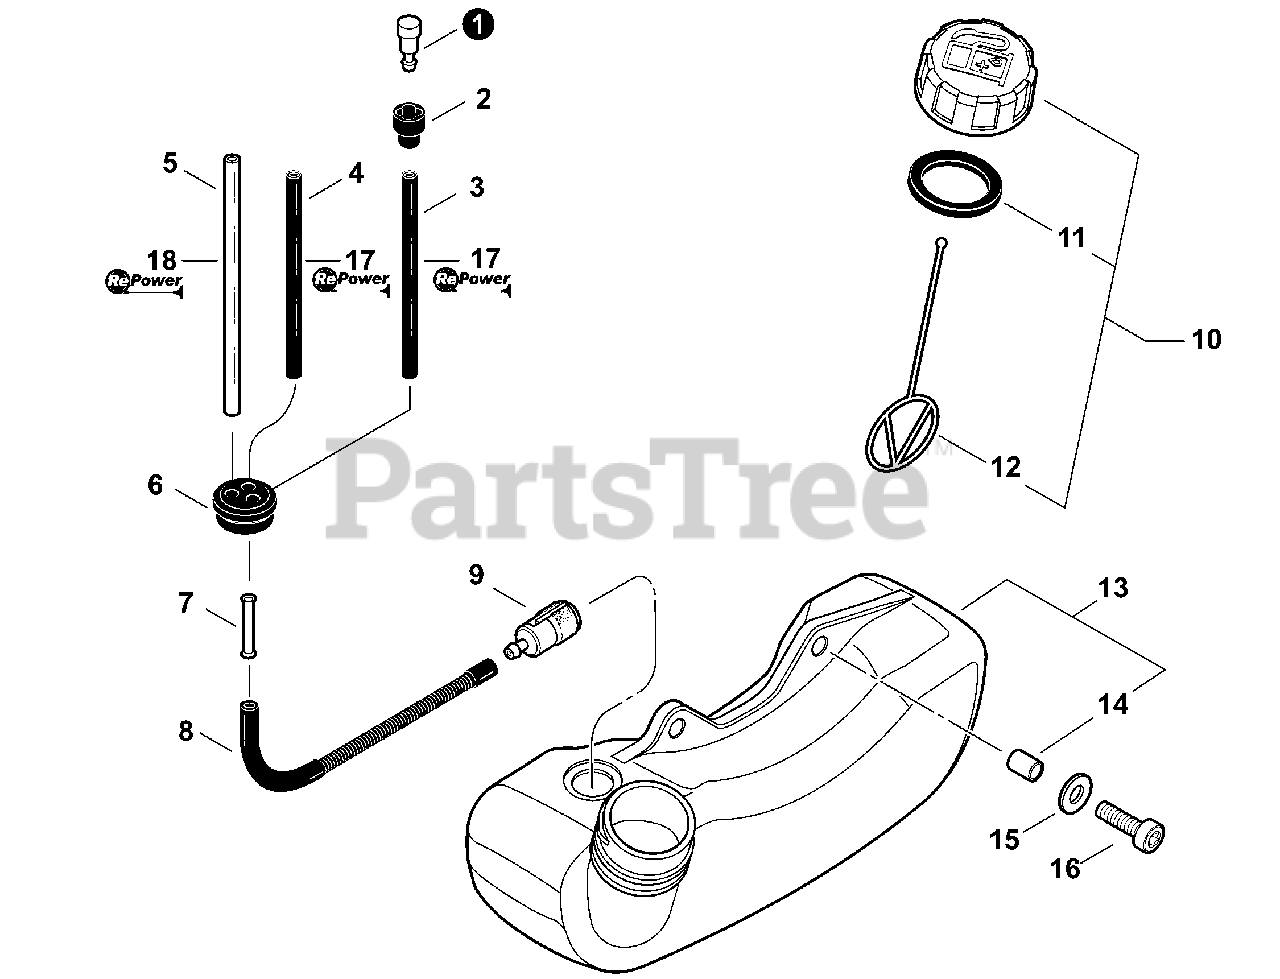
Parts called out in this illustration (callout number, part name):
1	VENT ASSY
2	HOLDER, VENT
3	PIPE, FUEL 3×5×70 BLACK
4	PIPE, FUEL 3×5×90 BLACK
5	PIPE, FUEL RETURN 3×6×90mm
6	GROMMET, FUEL 5
7	CONNECTOR, PIPE
8	PIPE
9	FILTER, FUEL
10	CAP ASSY, FUEL
11	GASKET, FUEL CAP
12	CONNECTOR, CAP L= 100mm
13	TANK ASSY, FUEL
14	SPACER 6.2×7.8×6
15	WASHER 5.5×12×0.8
16	BOLT 5×16
17	PIPE, BULK - REPOWER 3×5mm BLACK
18	PIPE, BULK - REPOWER 3×6mm CLEAR
